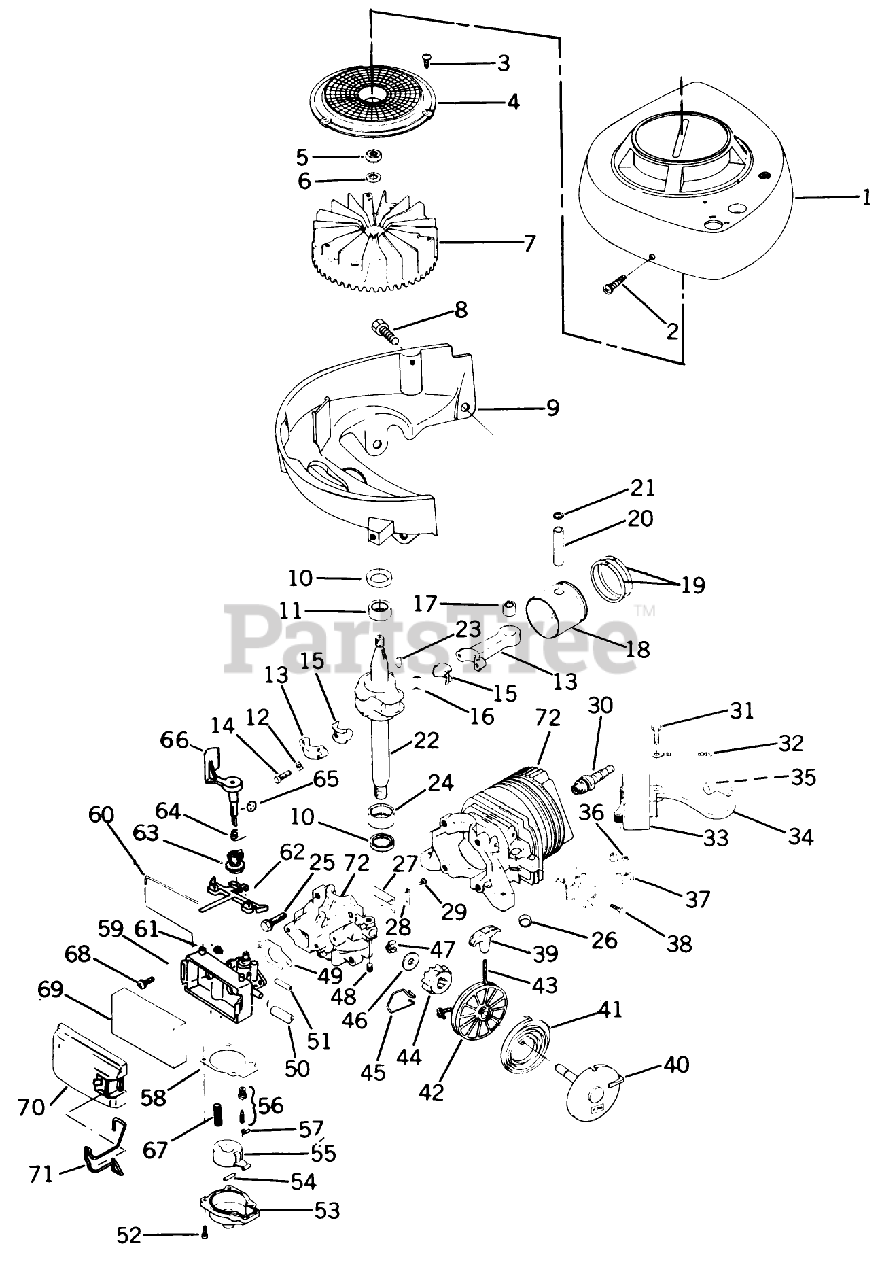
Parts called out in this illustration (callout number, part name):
2	SCREW F
3	SCREW F
8	SCREW-SEMS
11	BEARING V
14	SCREW
15	LINER ASM
17	BEARING AY F
21	RING-RETAINING
24	BEARING V
25	SCREW S
26	PLUG-CORE VF
28	PLATE-BACKUP, REED
34	HT LEAD&COVER XEV
36	NUT-CLIP
37	BRACKET S
39	HANDLE STARTER S
41	SPRING S
45	SPRING F
46	WASHER S
48	SET SCREW
49	GASKET CARB S
51	TUBING PRIMER S
52	SCREW-HH
60	RETAINER
61	F-SCREW CARB
63	COLLAR-ADJUST, AIRVANE
64	SPRING-THRO. S
65	DISC S
71	RETAINER-COVER, FILTER
